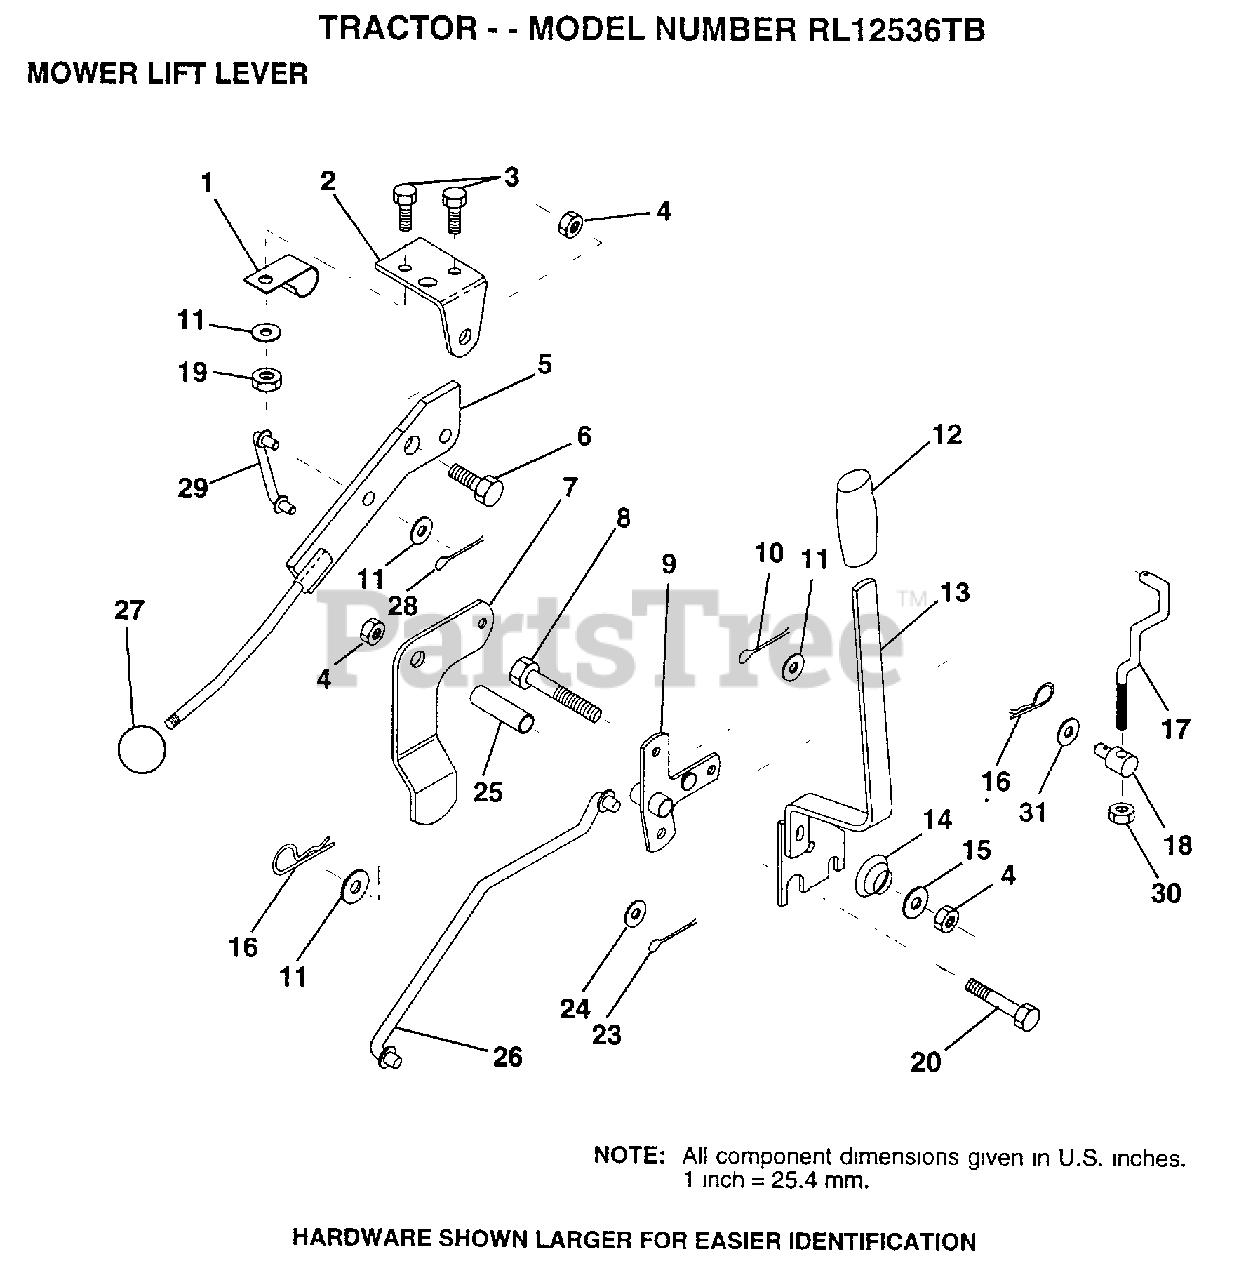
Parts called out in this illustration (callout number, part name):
1	"CLIP,INSULATOR"
2	BRKT CLUTCH
3	BOLT HXHD FIN
5	LEVER.ASM.CLUTCH
6	"BOLT, SHOULDER LT"
7	MWR CLUTCH ARM AS
8	BOLT
9	"BELLCRANK,LIFT"
10	COTTER PIN
11	WASHER
13	HANDLE.ASM.LIFT
14	SPRING COMPRESSIO
15	WASHER T
16	SPRING.RETAINER
17	"LINK,LIFT FRT"
18	TRUNION ADJ
20	BOLT
23	PIN COTTER 1/8
25	TUBE SPACER
26	ROD LIFT MOWER
27	KNOB T(3/8 HOLE)
29	CLUTCH LINK
30	NUT
31	WASHER
